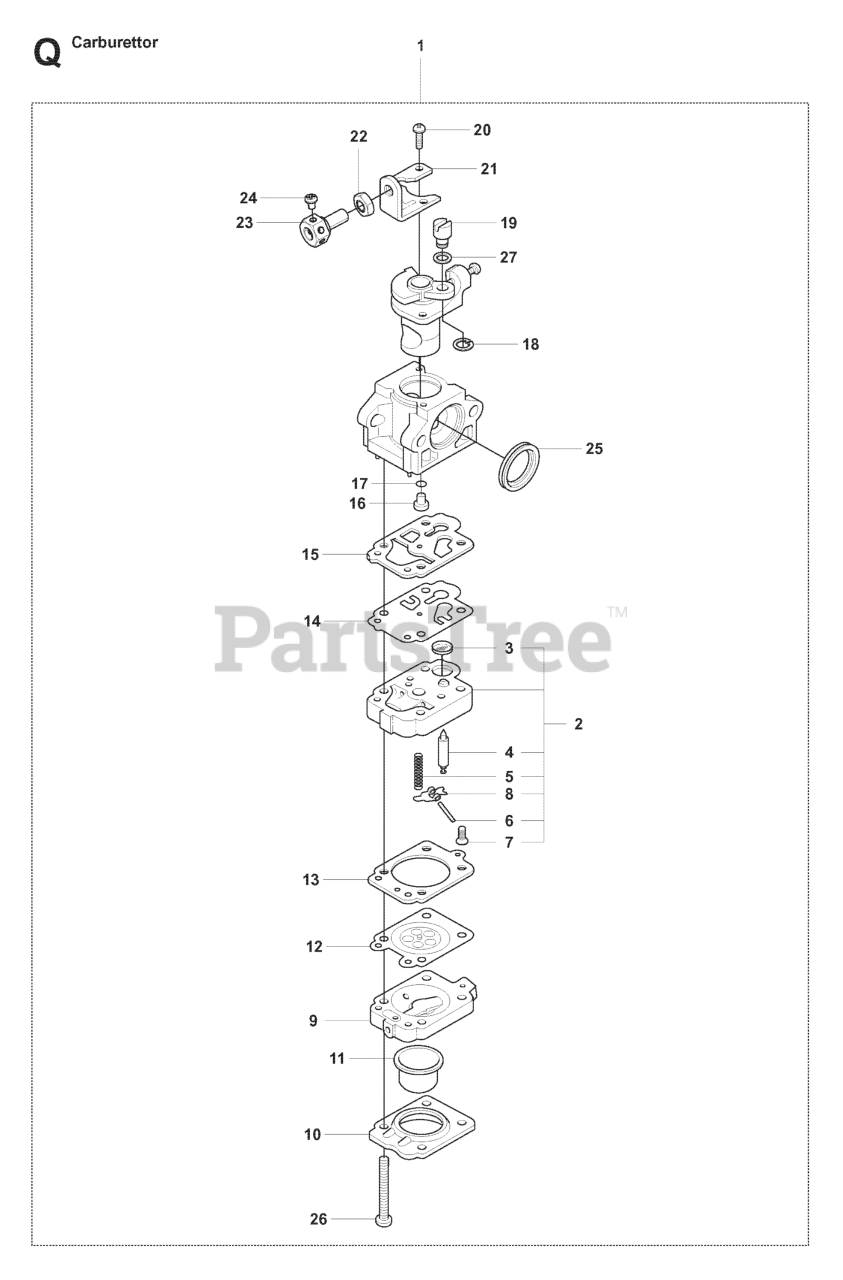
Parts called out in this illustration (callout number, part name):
15	GASKET
23	SCREW CABLE ADJUST
25	RING PACKING
